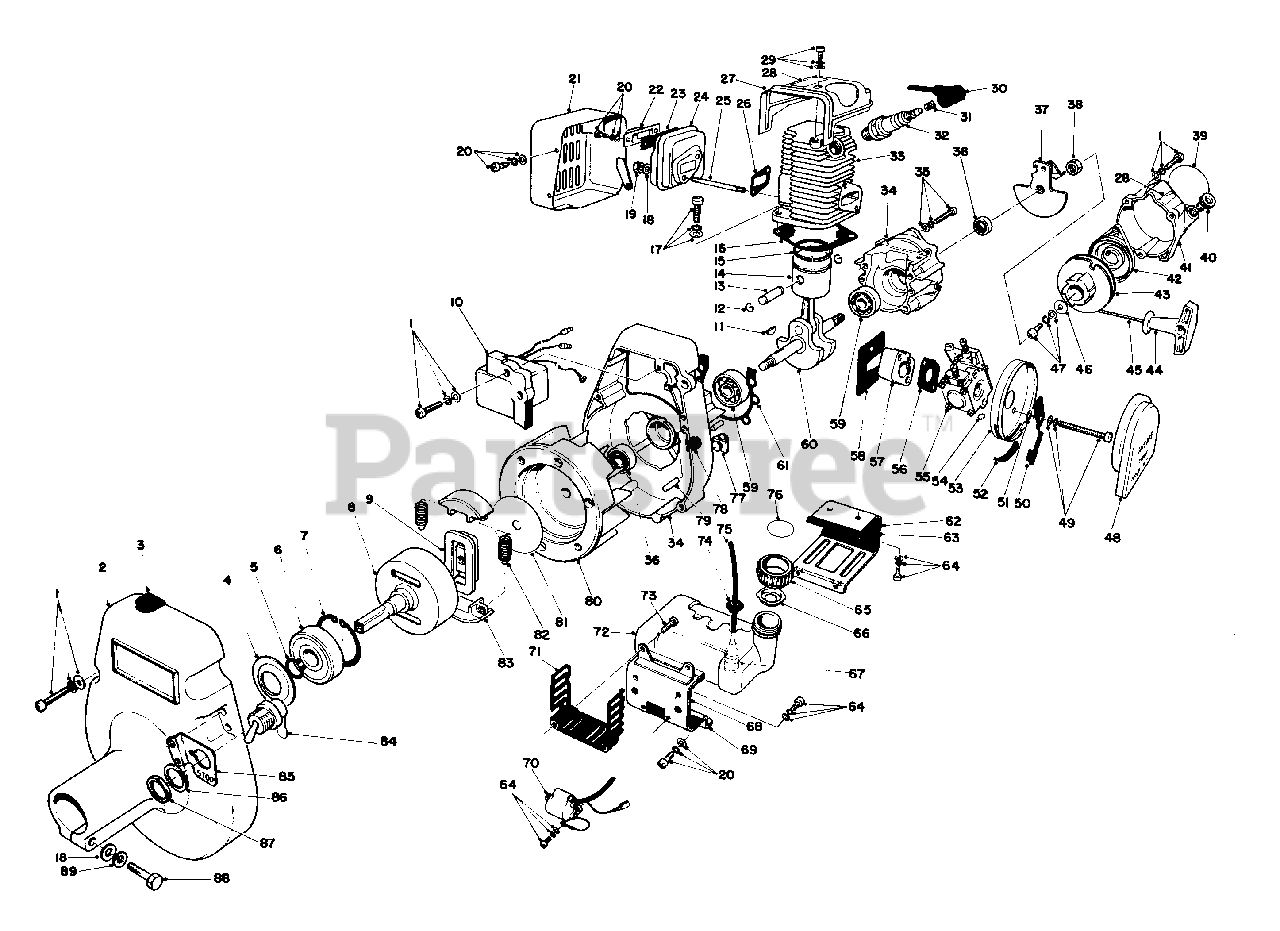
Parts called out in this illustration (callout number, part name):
1	Screw with Washer & Lockwasher
2	Fan Cover
5	Retaining Ring
6	Ball Bearing
7	Retaining Ring
8	Clutch Drum
9	Clutch Boss
10	Ignition Module
11	Woodruff Key
12	Circlip, Piston Pin
13	Piston Pin
15	Piston Ring
16	Gasket, Cylinder Base
17	Screw with Washer & Lockwasher
19	Locknut
20	Screw with Washer & Lockwasher
21	Muffler Cover
22	Lid-Muffler
24	Muffler Body
25	Stud Bolt
26	Gasket, Muffler
27	Cylinder Cover
28	Decal-Hot Surface
29	Screw with Washer & Lockwasher
30	Cap-Spark Plug
31	Coil Spring-Plug Cap
33	Cylinder
34	Crankcase Set
35	Screw with Washer & Lockwasher
36	Oil Seal
37	Ratchet Assembly
40	Rope Guide
41	Starter Case
42	Rewind Spring
43	Recoil Drum
44	Starter Handle
45	Starter Rope
47	Screw with Lockwasher
48	Air Filter
49	Screw with Washer & Lockwasher
50	Choke Shutter
53	Case-Air Cleaner
54	Clip-Fuel Pipe
55	Carburetor Assembly
56	Gasket
57	Insulator
60	Crankshaft Assembly
61	Gasket-Crankcase
62	Bracket-Fuel Tank
64	Screw with Washer & Lockwasher
65	Cap-Fuel Tank
66	Check Valve
67	Fuel Strainer
69	Bracket-Fuel Tank
70	Ignition Coil
71	Dust Filter
72	Fuel Tank
73	Self Tapping Screw
75	Fuel Pipe
76	Decal Fuel Mix
77	Cord Holder
79	Pin-Knock
80	Flywheel
81	Side Plate
82	Clutch Spring
83	Clutch Shoe
84	Switch (Incl. Ref. #86 & 87)
85	Bracket-Switch
86	Washer
87	Nut
89	Lockwasher
